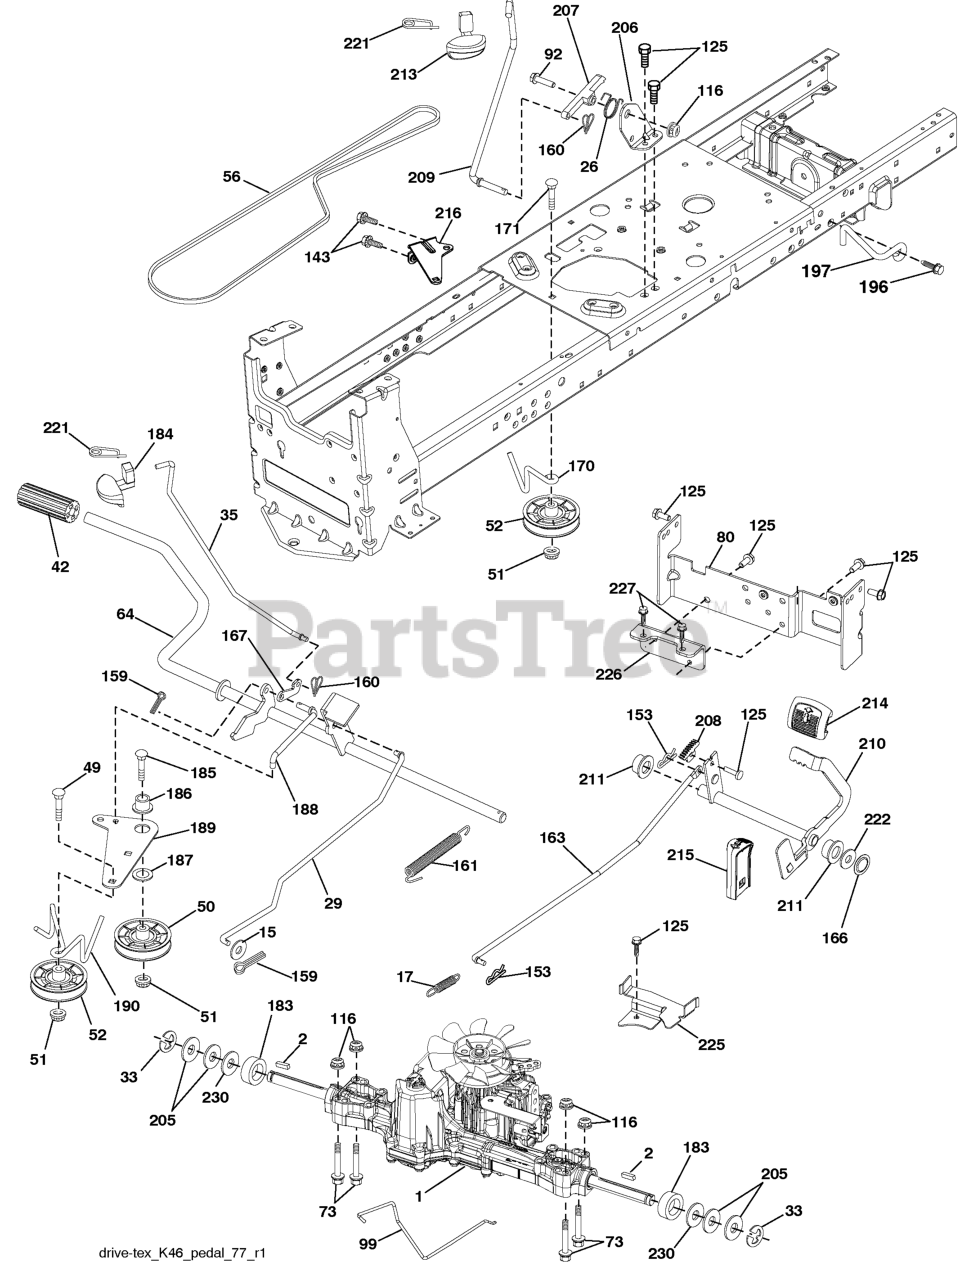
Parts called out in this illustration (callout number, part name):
1	Transaxle, TUFFTORQ K46 BT (See Transaxle breakdown)
2	SQUARE KEY
15	WASHER
17	SPRING.BRAKE.K46.GREEN
26	SPRING.RETURN.CRUISE
29	ROD.BRAKE.K46
35	ROD.BRAKE.PARKING.GT.H
42	PEDAL COVER T
50	IDLER.FLAT.910.OFFSET
51	NUT LOCK FLG 3/8-16 UNC
52	IDLER.V-GROOVE.910.OFFSET
56	V-BELT.MOWER.92.40.42/K46
64	SHAFT.ASM.PEDAL.BRK.CNTR
73	BOLT HEX 5/16-18 GR 5
80	STRAP TORQUE
92	BOLT
99	ROD.SPRING.BYPASS.K46.LT.Z
116	NUT LOCK HEX FLANGE 5/16-18
125	SCREW
143	Screw 5/16-18 x 1/2
153	RETAINER M
159	COTTER PIN
160	RETAINER CLIP
161	SPRING, RETURN LT
163	ROD.CONTROL.PEDAL.K46
166	NUT.PUSH.625
167	LATCH.BRAKE.SPRING
170	KEEPER.V-IDLER.CENTER.
171	BOLT
183	SPACER AXLE
184	HANDLE.PARKG.BRK.HUSQ X667
186	SPACER.RETAINER
187	WASHER 12/32X2X10GA
188	RP.LINK.CLUTCH.GROUND.DRIVE
189	BELLCRANK.GROUND.DRIVE.TEX.
190	KEEPER.BELLCRANK.DRIVE
196	SCREW 3/8-16X1
197	LINK.CLUTCH.ANIT-ROTAT
206	BRKT.MOUNT.LATCH.CRUIS
207	LATCH.CONTROL.CRUISE
208	GEAR.SECTOR.CONTROL.CR
209	ROD.CONTROL.CRUISE.GT.
210	ROCKER.ASM.PEDAL.CONTR
211	BEARING.NYLON
213	KNOB.CONTROL.CRUSIE.HU
214	PEDAL.FORWARD.PAD.TEX
215	PEDAL.REVERSE.TEX.GT.4
216	BRACKET.PULLEY.IDLER.W/TEX
221	RETAINER.SPRING.CLIP.H
222	WASHER 21/32 X 1-1/4 X 10 GA.
225	KEEPER.BELT.TRANSAXLE.K46
226	BRACKET.MOUNT.TORQUE.K46.TLT
227	SCREW.THDROL.5/16-18X3/4.TTY
230	WASHER.HARDENED
